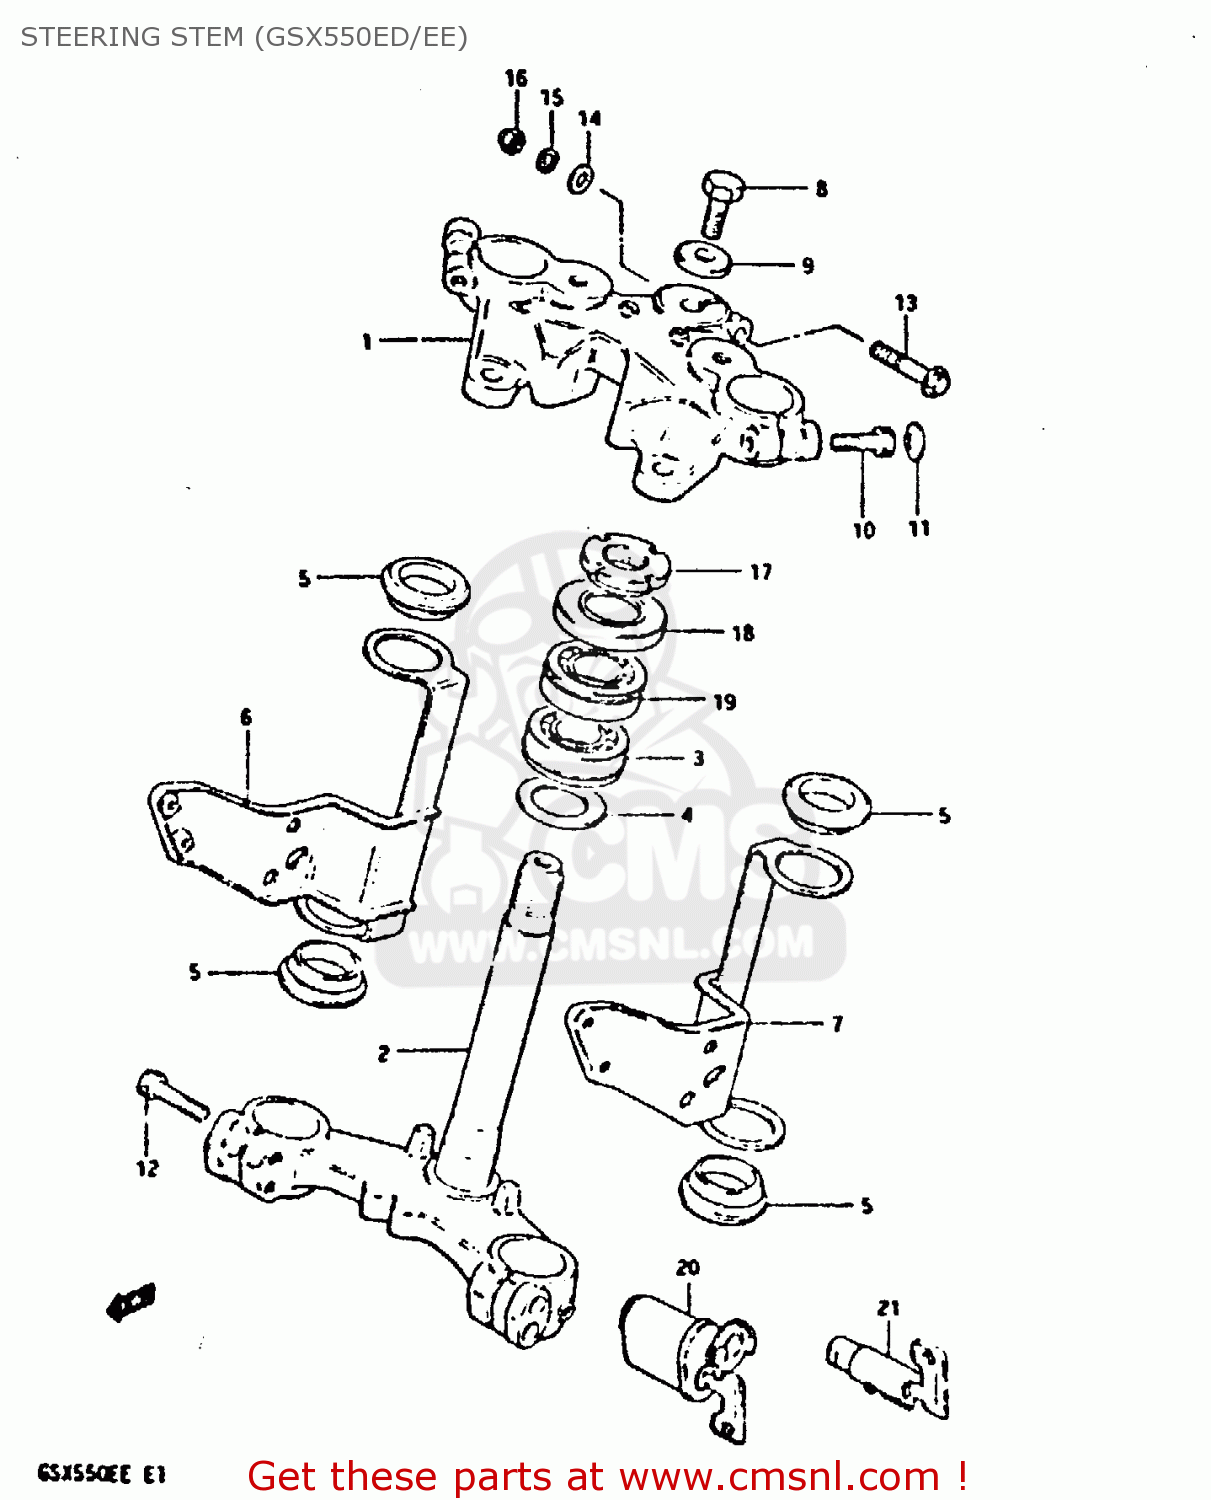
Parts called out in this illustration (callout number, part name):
1	HEAD,STEERING STEM
2	STEM,STEERING
3	BEARING
4	WASHER,THRUST
5	CUSHION,HEADLAMP BRACKET
6	BRACKET,HEADLAMP,RIGHT
7	BRACKET,HEADLAMP,LEFT
8	NUT,STEM HEAD
9	WASHER,STEERING STEM B
10	BOLT
11	CAP(OD:20)
12	BOLT, REAR (8X30)
13	BOLT, UPPER
14	WASHER,8.5X16X
15	LOCK WASHER
16	NUT,M8X1.25X12
17	NUT,STEERING STEM
18	DUST SEAL,STEERING UPR
19	TAPER,ROLLER BEARING
